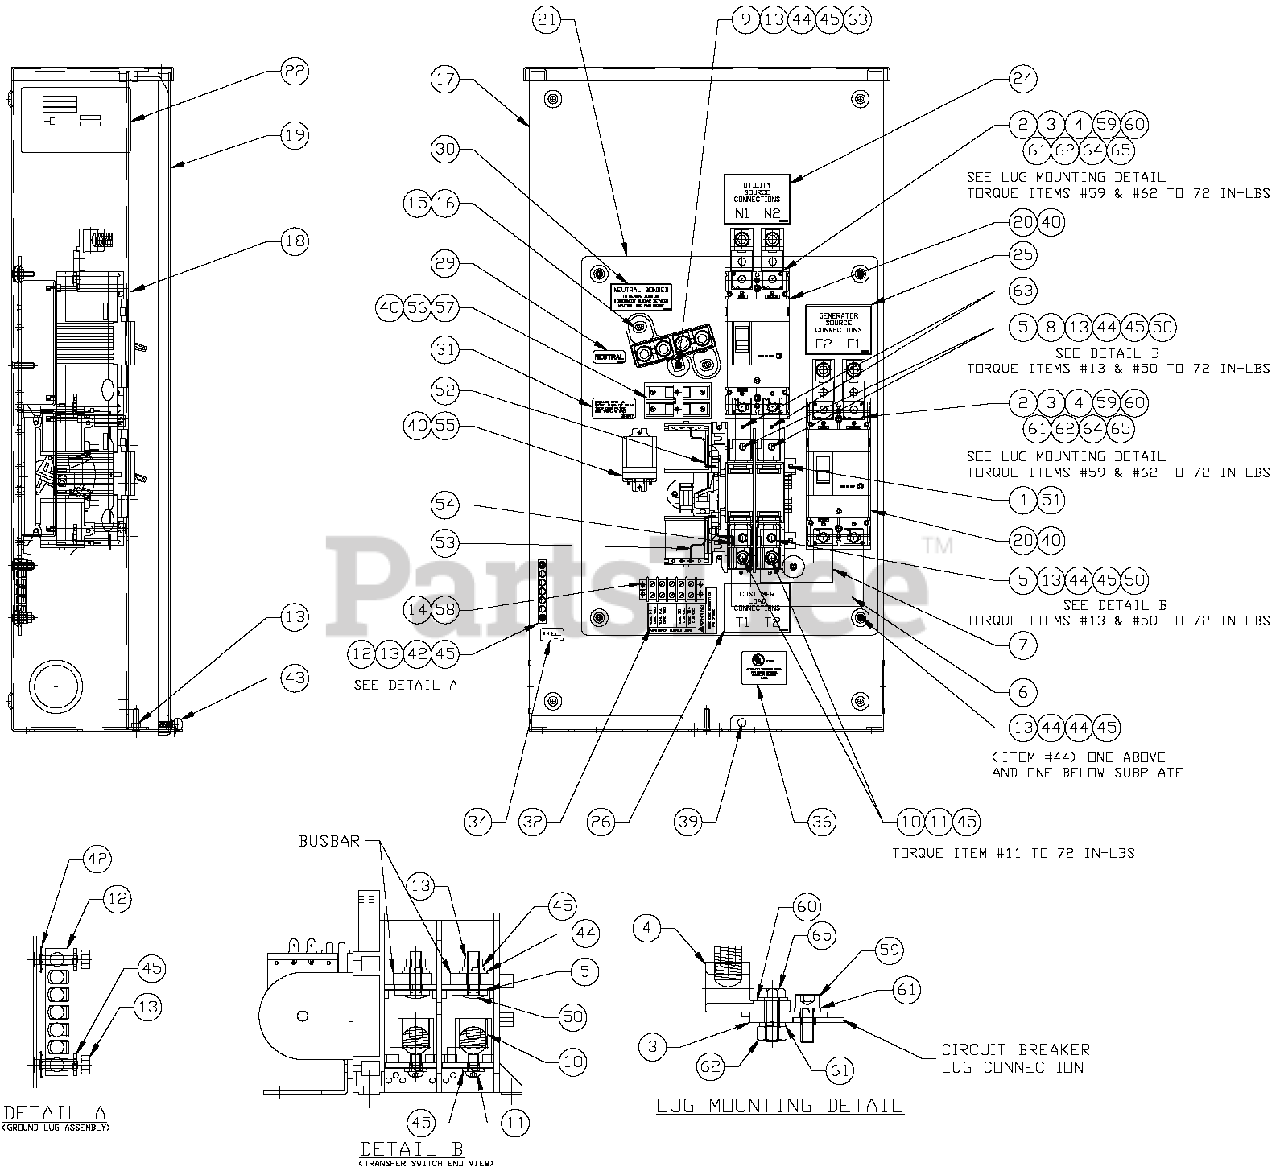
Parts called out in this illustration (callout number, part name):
1	TRANSFER SW. HSB 200A 2P 250V
2	CIRCUIT BREAKER, 200A 2-POLE
3	BUSBAR, 200A LUG ADAPTER
4	LUG 300 MCM-6STR
5	SPACER 200 AMP TRANSFER
6	BUSBAR, 200A TRANSFER SW E1
7	BUSBAR, 200A TRANSFER SW E2
8	BUSBAR, 200A TRANSFER SW N1,N2
9	BUSBAR, NEUTRAL BLOCK
10	LUG SOLDERLESS 250-#6 AL/CU
11	SCREW BHSC 1/4-20 X 3/8
12	GROUND BAR (5) 2-14 AWG CONN
13	NUT HEX 1/4-20 SS
14	RIVET, POP .156 X .67
15	ASSY-NEUT BLK 200-400A W/TAP
16	SCREW HHTT M6-1.0 X 12 MM
17	ENCLOSURE, 200A SE XFER SW
18	COVER, INSIDE 200A DUAL BREAKER
19	COVER, TRANSFER SWITCH
20	RISER, CIRCUIT BREAKER
21	SUBPLATE, 200A SE XFER SW
22	DECAL, TRANSFER SWITCH DATA
24	DECAL, UTILITY SOURCE CONN
25	DECAL, GENERATOR SOURCE CONN
26	DECAL, CUSTOMER LOAD CONN
29	DECAL, NEUTRAL
30	DECAL, NEUTRAL CONNECTION
31	DECAL, FUSE REPLACEMENT
32	DECAL, TERMINAL STRIP
34	DECAL, GROUNDING LUG
36	DECAL, UL LIST HSB
39	NUT TRIC 1/4-20 X .525
40	SCREW PHTT M4-0.7 X 12 ZYC
42	WASHER SHAKEPROOF EXT 1/4 STL
43	THUMB SCREW 1/4-20x1/2
44	WASHER FLAT 1/4-M6 ZINC
45	WASHER LOCK M6-1/4
50	BOLT CARR 1/4-20 X 1"
51	SCREW HHTT M5-0.8 X 10 BP
54	WIRE-E1
55	RELAY PNL 12VDC DPDT
56	FUSEBLOCK 30A 600V 2 POLE
57	FUSE 5A X BUSS HLDR73591
58	BLOCK TERM 20A 5 X 6 X 1100V
59	SCREW SHC M8-1.25 X 20 G8
60	WASHER FLAT 5/16-M8 ZINC
61	WASHER LOCK M8-5/16
62	NUT HEX M8-1.25 G8 CLEAR ZINC
63	SCREW HHTT #8-32 X 1/4 CZ
64	SCREW RHM #8-32 X 3-1/4
65	SCREW HHC M8-1.25 X 25 C8.8
